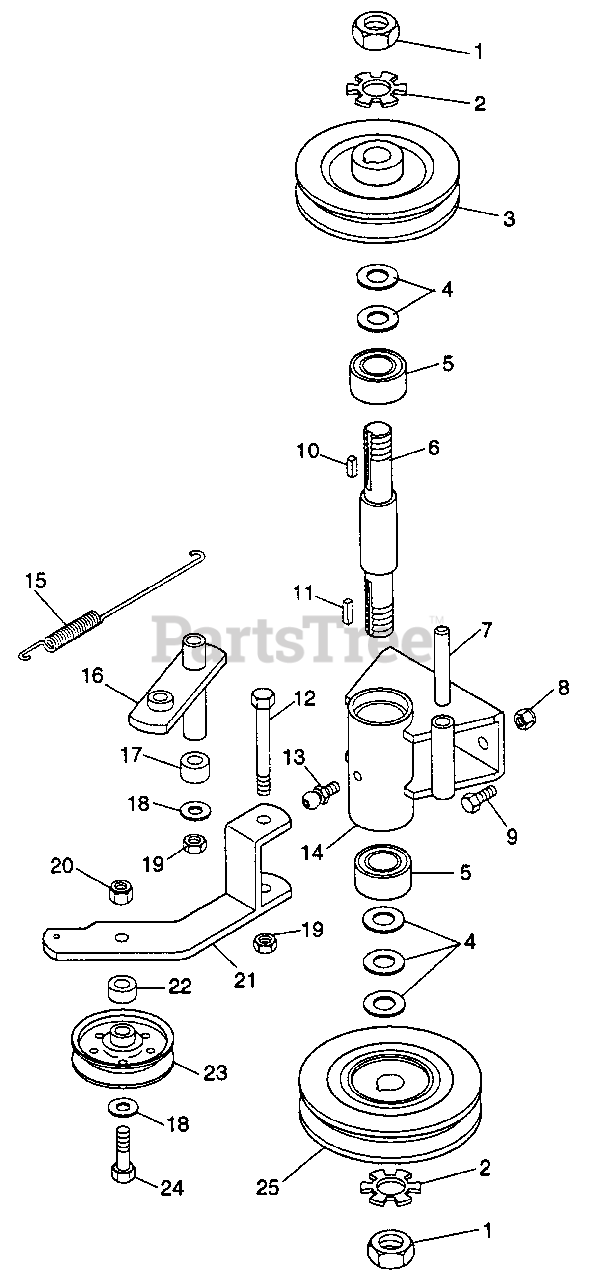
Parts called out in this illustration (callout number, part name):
1	Nut-Hex-Jam .750-10 Heavy
2	Star Washer
3	Sheave
4	Wshr-Fl-Stl .755 x 1.250 x .125
5	Brg-Ball .750 x 1.781 x .61
6	Jack Shaft
7	Tube
8	Nut-Lk-Nyl .312-18 Pl
9	Blt-Hex .31-18 x 1.00 Pl Gr 5
10	Key-Sq 1.865 x .50 x 1.865
11	Key-Str .186 x .75 x .186
12	Blt-Hex .38-16 x 3.00
13	Spin Drive Zerk Fitting
14	Spindle
15	Sg-Tens .095 x .62 x 9.25
16	Spring Arm
18	Wshr-Fl-Stl .406 x .812 x .065 Pl
19	Nut-Lk-Ctr .375-16 Typ N
20	Nut-Lk-Nyl .375-16 Pl
21	Idler Arm
22	Bushing .406 x .750 x .188
23	Idler-Ply
24	Blt-Hex .38-16 x 2.00 Pl Gr 5
25	Sheave
